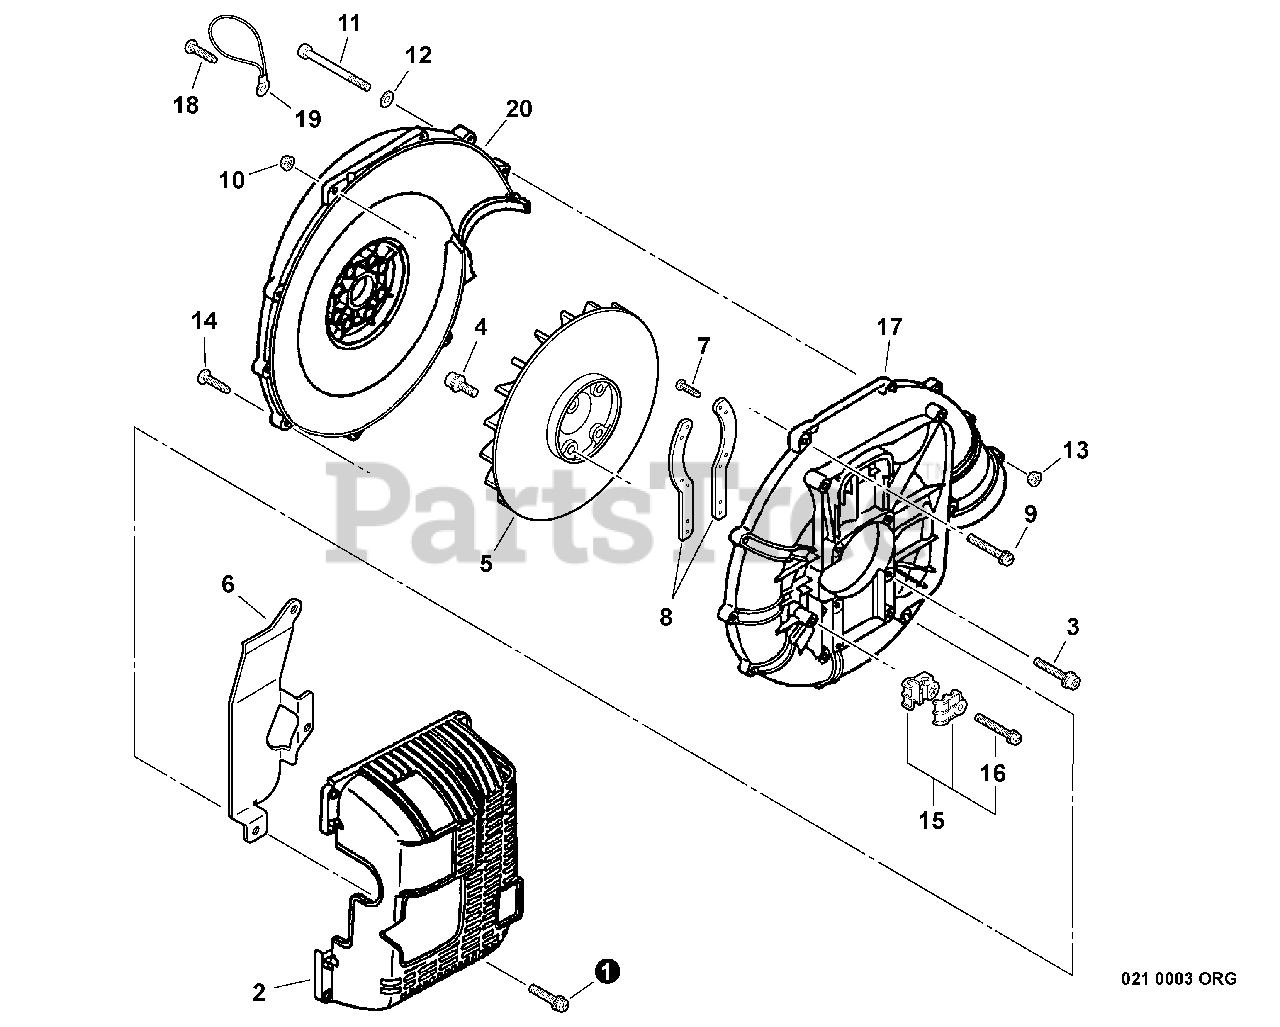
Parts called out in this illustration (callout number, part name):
1	SCREW - 5X18
2	COVER, ENGINE
3	SCREW - 5X32
4	SCREW - 5X20
6	INSULATOR
7	SCREW - 3X12 -- TAPPING
8	BRACKET, ENGINE
9	SCREW - 5X40
10	NUT - 5 -- FLANGE
11	SCREW - 5X60
12	WASHER - 5
13	NUT - 5 -- FLANGE
14	SCREW - 5X30
15	CABLE HOLDER KIT
16	SCREW - 5X25
17	COVER, FAN - OUTER
18	SCREW - 5X16 -- TAPPING
19	STRAP, SAFETY
20	COVER, FAN - INNER
